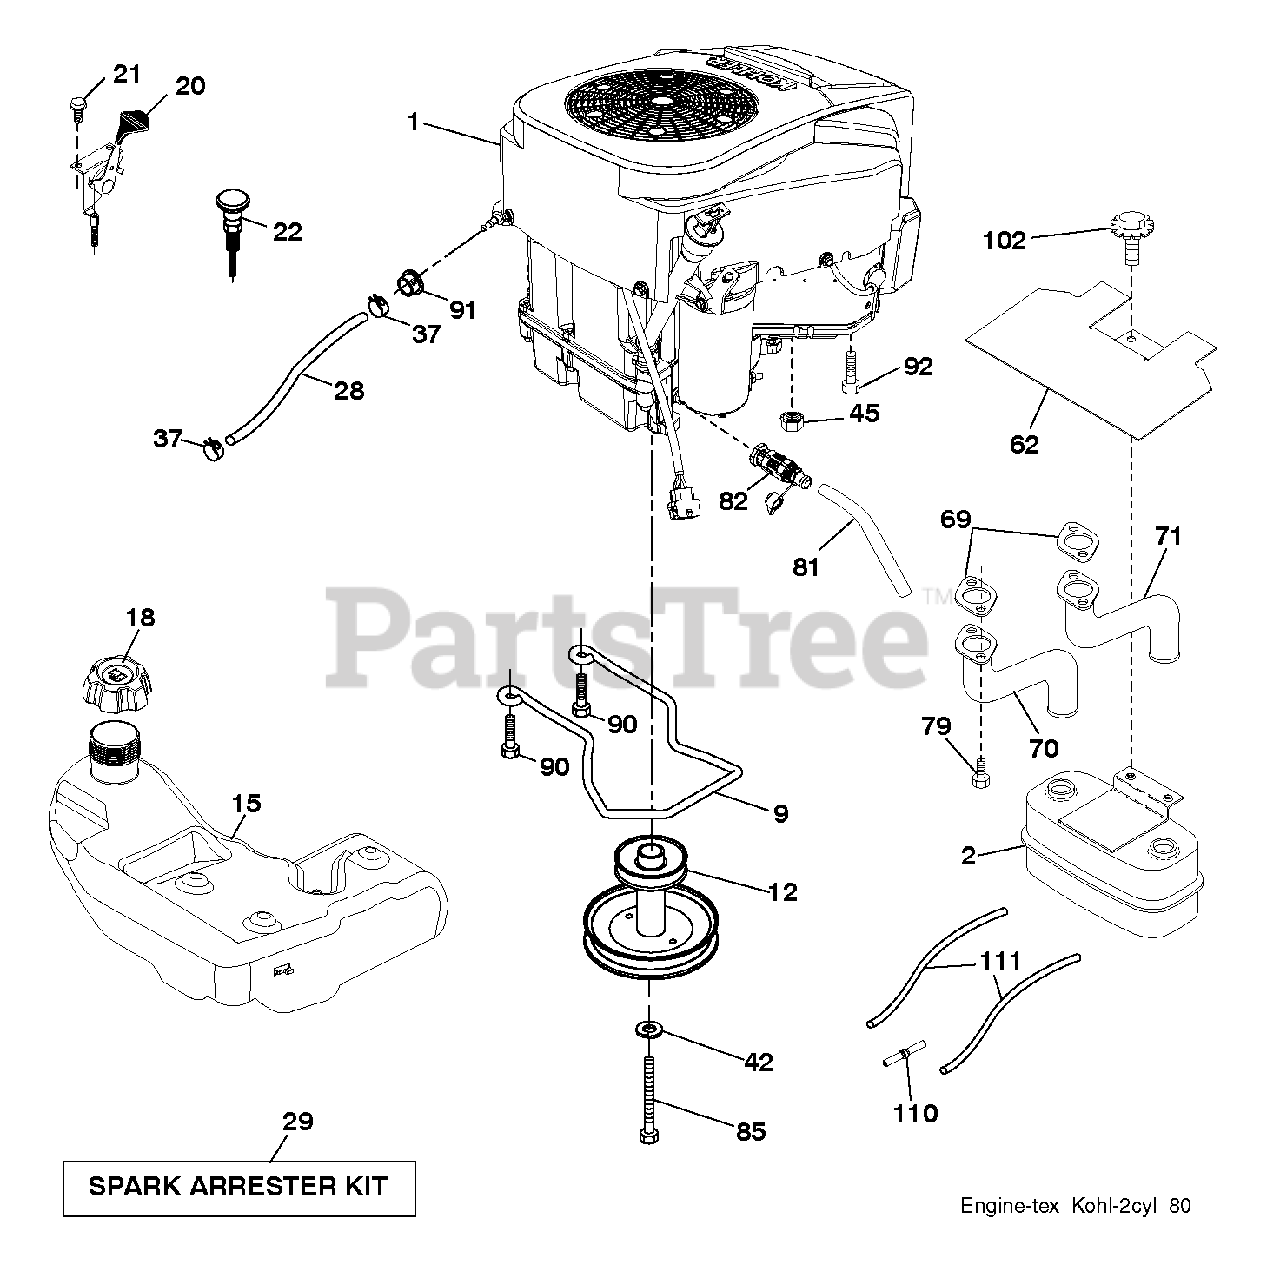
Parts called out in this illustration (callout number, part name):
2	Muffler Assembly, Twin MN
9	KEEPER.BELT.ENG.4.25"2.BLT.431
12	PULLEY.ENGINE
15	Fuel Assembly Tank, 3 Gallon
18	CAP ASSY FUEL 3" GRAY
20	THROTTLE CONTROL
21	SCREW.#10 X 0.750.BOS
22	CONTROL.CHOKE.ERGO.PUSH-IN.BLA
28	Fuel Hose, 1/4" Low Perm
29	KIT.SPARK ARRESTOR 794945 B&S
37	HOSE CLAMP
42	WASHER 7/16 LOCK
45	NUT
62	SHIELD.HEAT.MUFFLER
69	GASKET.EXHAUST.KOHL.CV18-CV26
70	PIPE.EXHAUST.RH.CV18/20
71	PIPE.EXHAUST.LH.CV18/20
79	SCREW.SOCKET HD.5/16-1
81	TUBE, DRAIN OIL ASM.
82	VALUE.OIL.DRAIN
85	BOLT.HEX.7/16-20X4.GR5.1.5BLUE
90	SCREW 3/8-16X1
91	BUSHING.1.375OD
92	SCREW 3/8-16X1
102	SCREW
110	VALVE.ASM.ANTI-SLOSH
111	RP PURGE LINE
